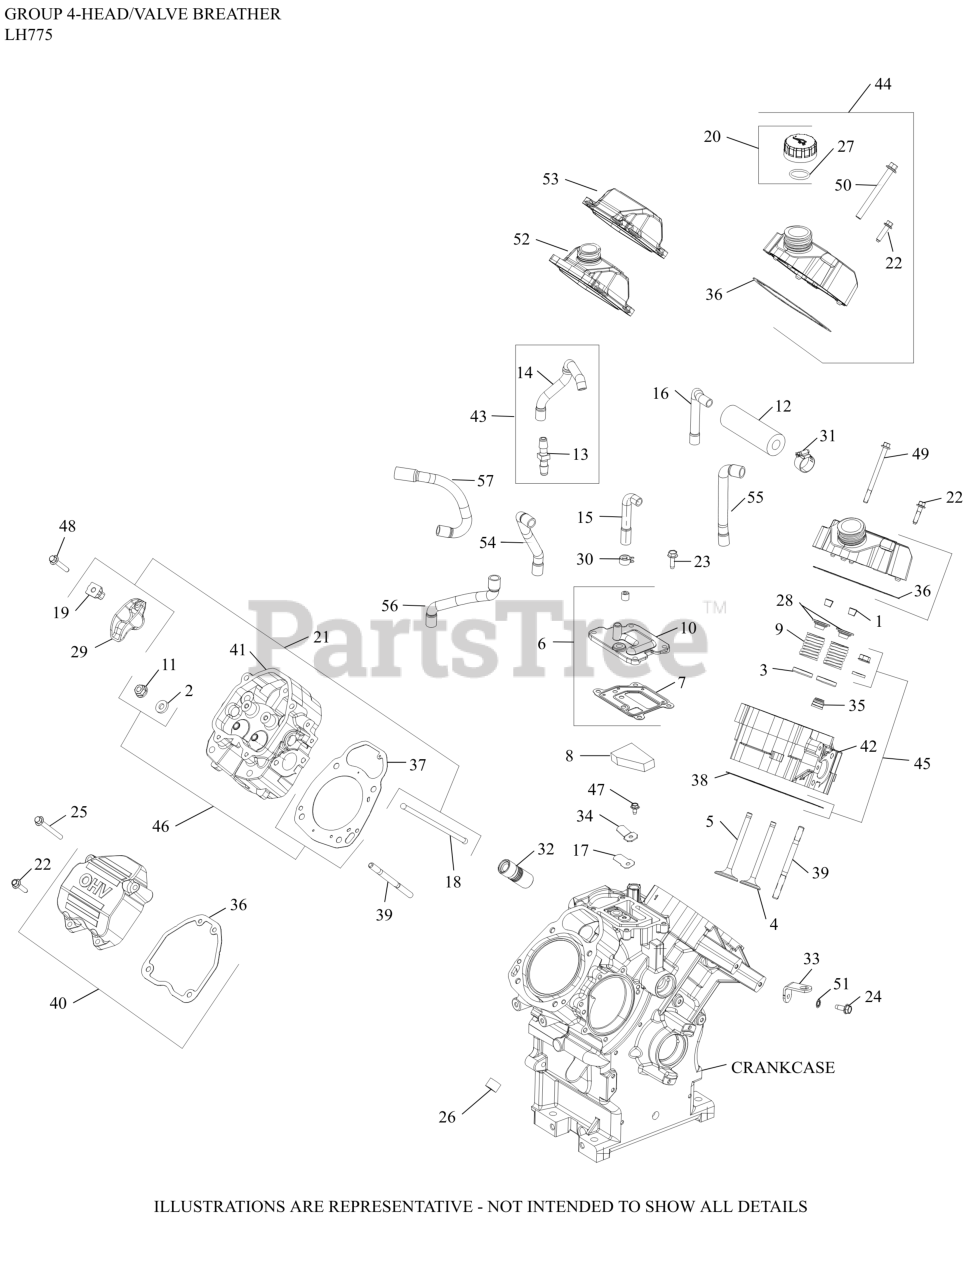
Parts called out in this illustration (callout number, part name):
1	KIT, RETAINER
2	WASHER, FLAT 5/16"
3	RETAINER, SPRING
4	VALVE, EXHAUST
5	VALVE, INTAKE (STD)
5	VALVE, INTAKE (.25)
5	VALVE, EXHAUST (.25)
7	GASKET, BREATHER
8	FILTER, BREATHER
9	SPRING, VALVE
10	COVER, BREATHER
11	NUT, FLG M8X1.25
12	INSULATOR, BREATHER HOSE
16	HOSE, BREATHER
17	REED, BREATHER-(#2440206S)
17	REED, BREATHER
18	ROD, PUSH
19	PIVOT, ROCKER ARM
20	KIT, OIL FILL CAP (YELLOW)
21	KIT, VALVE TRAIN
22	SCREW, FLG M6X1.0X25
23	SCREW, THREAD FORMING
24	SCREW, THREAD FORMING
25	SCREW, FLG M6X1.0X55
26	PLUG, PIPE CTSK 3/8"
27	O-RING, DIPSTICK
28	CAP, VALVE SPRING
29	ARM, ROCKER
30	SPRING CLAMP, HOSE
31	CLAMP, HOSE (KM)-USE 25 237 31-S
32	LIFTER, VALVE HYDRAULIC-USE 25 351 11-S
34	RETAINER, REED
35	SEAL, VALVE BAND
36	GASKET, VALVE COVER
38	KIT,CYL HD GASKET #2SIDE-USE 66 841 04-S
40	KIT, ROCKER COVER
41	KIT, CYLINDER HEAD (#1 SIDE)
42	KIT, CYLINDER HEAD (#2 SIDE)
44	KIT, LH OIL FILL VALVE COVER
47	SCREW, FLG THD FRM M5X.8X10
48	SCREW, FLG (BLACK) M6X1.0X34
49	SCREW, FLG M6X1.0X80
